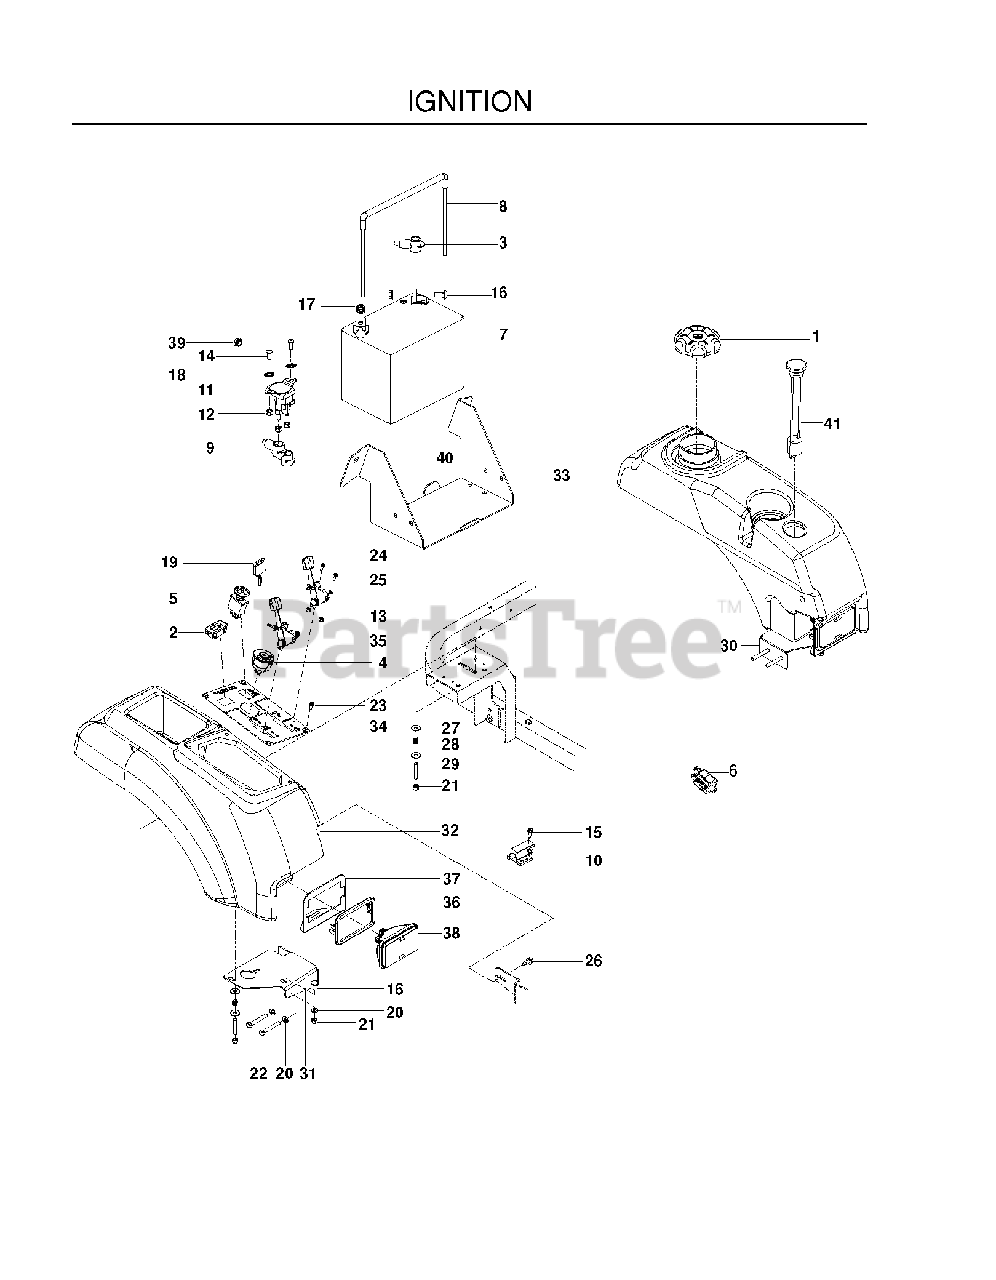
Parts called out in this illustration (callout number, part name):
1	FUEL CAP, GENERIC
2	HOUR METER
3	INSULATOR
4	IGNITION SWITCH
5	SWITCH, BLADE
6	SWITCH, BRAKE 3P
7	BATTERY, 12 V 330 AMP TBR
8	BATTERY TIE DOWN ASSEMBLY
9	TERMINAL COVER-SM
10	SWITCH, INTERLOCK
11	SOLENOID
12	NUT 1/4-20 NYLOC
13	NUT 10-24 NYLOC
14	SCR 1/4-20 X 5/8 BTN SKT HD ZD
15	SCREW #10 X 1/2 SELF TAPPING
16	BOLT 5/16C X 3/4" CARRIAGE
17	5/16-18 NYLOC FLANGE NUT
18	WASHER 1/4 INT TOOTH
19	KEY
20	FLAT WASHER 5/16 SAE
21	NUT 5/16 NYLOC
22	CAPSCREW
23	SCREW 1/4 X 5/8
24	CABLE THROTTLE
25	SCREW #10-24 X 5/8
26	BOLT 5/16-18 X 3/4
27	WASHER 5/16 FLAT
29	STUD, 5/16C
30	SUPPORT, RAM TANK, LT BLK
31	SUPPORT, RAM TANK, RT BLK
32	FENDER-RH
33	FUEL TANK ASM.
34	DECAL, CONTROL PANEL RAM
35	CABLE CHOKE
36	HEADLIGHT BEZEL
37	BRACKET HEADLIGHT.
39	JAM NUT 1/4C
40	BOX, BATTERY, BLACK
41	FUEL GAUGE W/GROMMET
